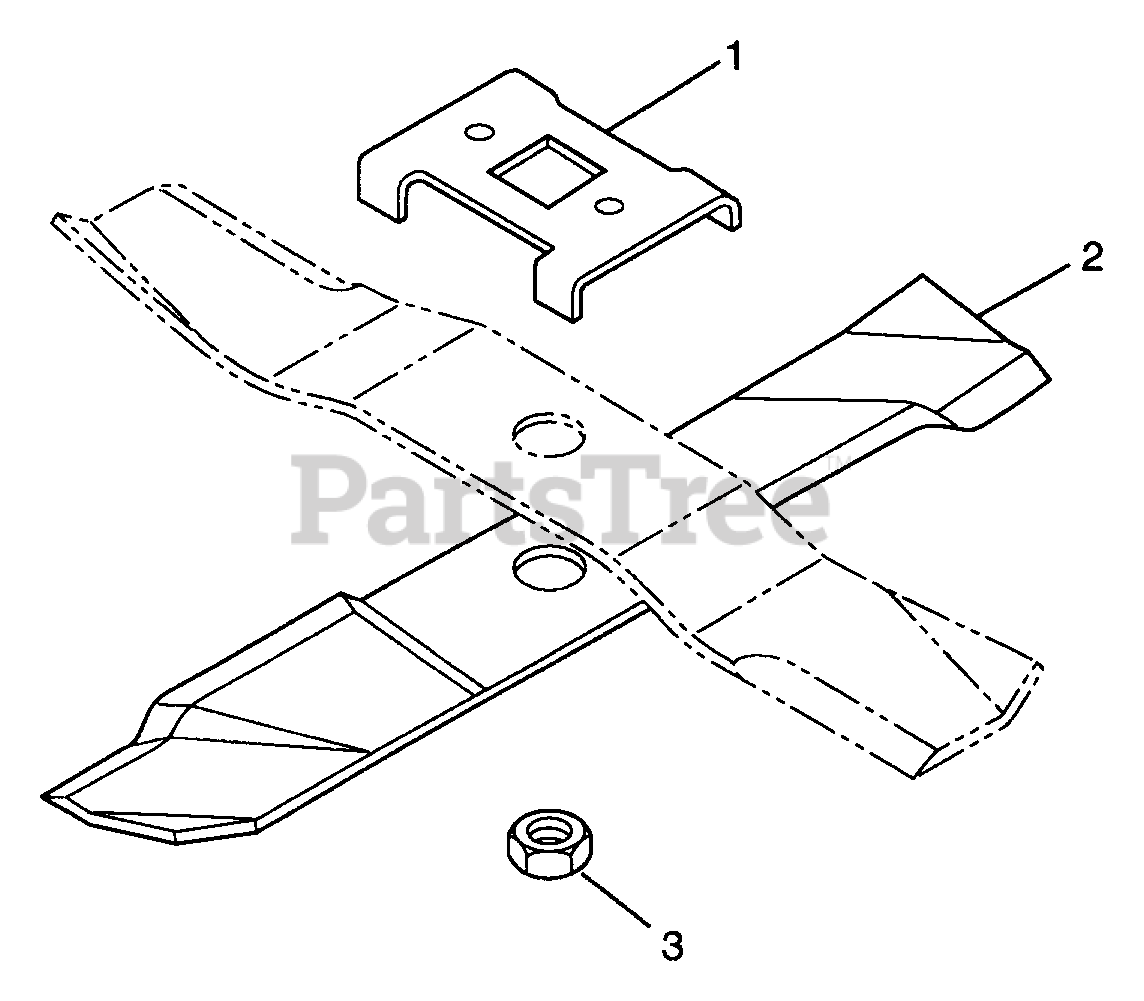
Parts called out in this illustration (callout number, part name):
1	BLADE TRAY - GT 42
2	M BLADE 42
3	NUT-LK-JAM-NYL .75-10 PL
